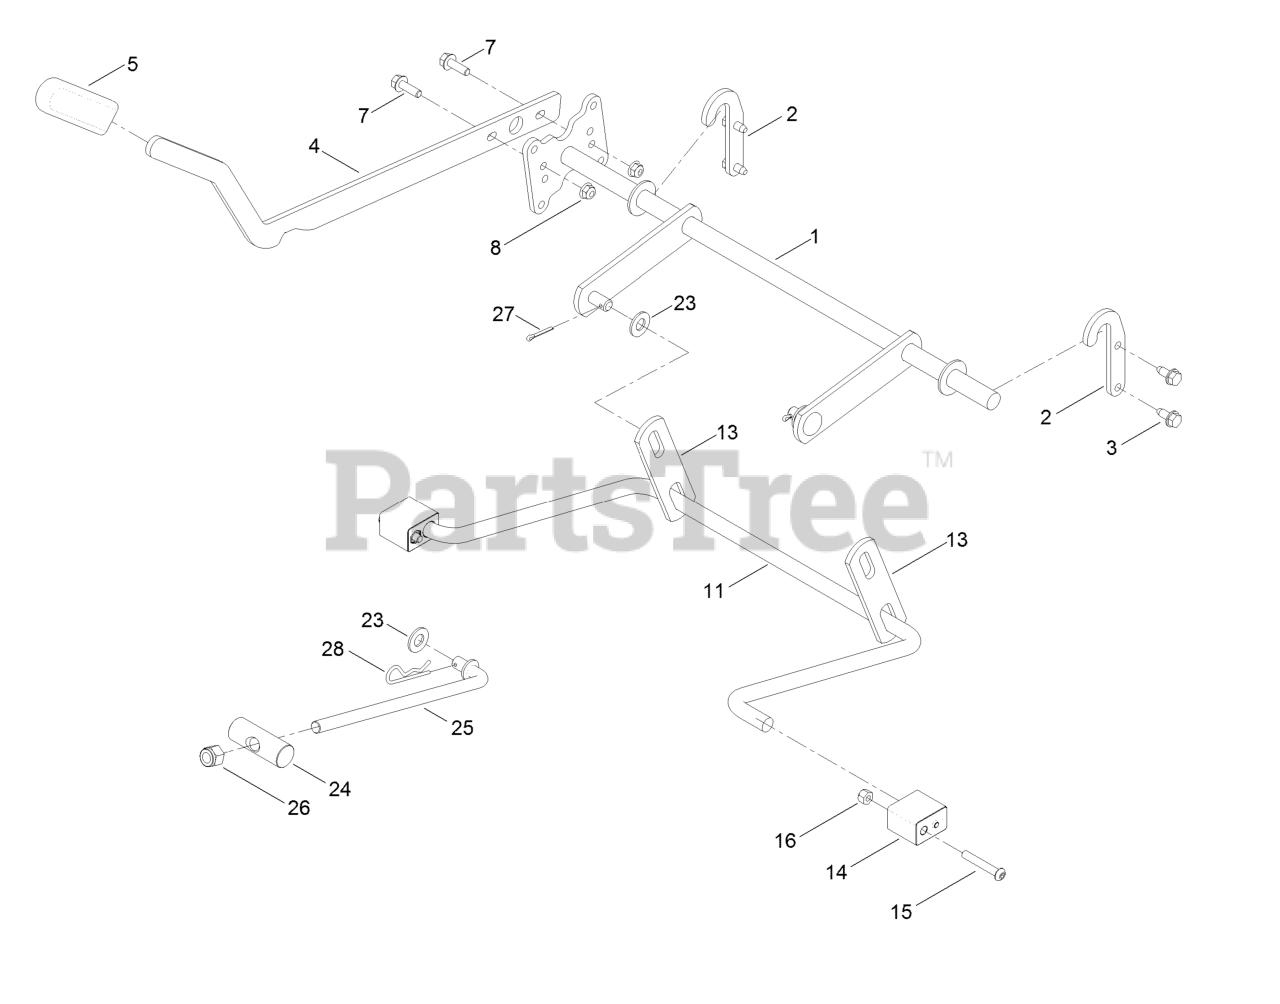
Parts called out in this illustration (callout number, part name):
1	LIFT-DECK, NARROW
2	BRACKET-LIFT
3	Screw-HWH 5/16-18 X 3/4 Tf
4	LEVER-LIFT
5	GRIP-LEVER
7	SCREW-HHF
8	NUT-HF, NI
11	ARM-LIFT, REAR
13	LINK-LIFT
14	BLOCK-PIVOT
15	SCREW-HSBH
16	NUT-LOCK, NI
23	WASHER-FLAT
24	PIN-PIVOT
25	ROD-MOUNT, DECK
26	NUT-HEX
27	PIN-COTTER
28	PIN-COTTER
